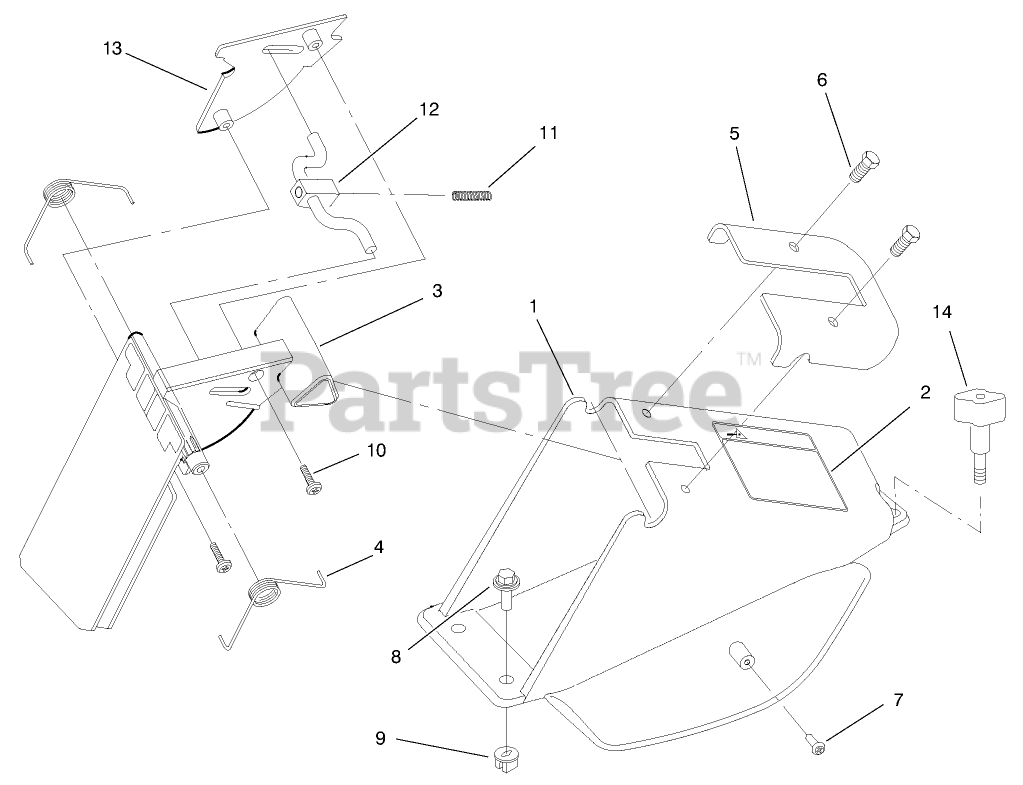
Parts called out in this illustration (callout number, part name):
1	ASM - CHUTE W/DECAL
2	DECAL - CAUTION DOOR
3	DOOR-DISCHARGE
4	SPRING-DOOR, RH
6	SCREW-PLASTITE
7	SCREW-PPH
8	SCREW-HWH
11	SPRING-COMPRESSION, LATCH
12	LATCH-DOOR
13	DOOR COVER
